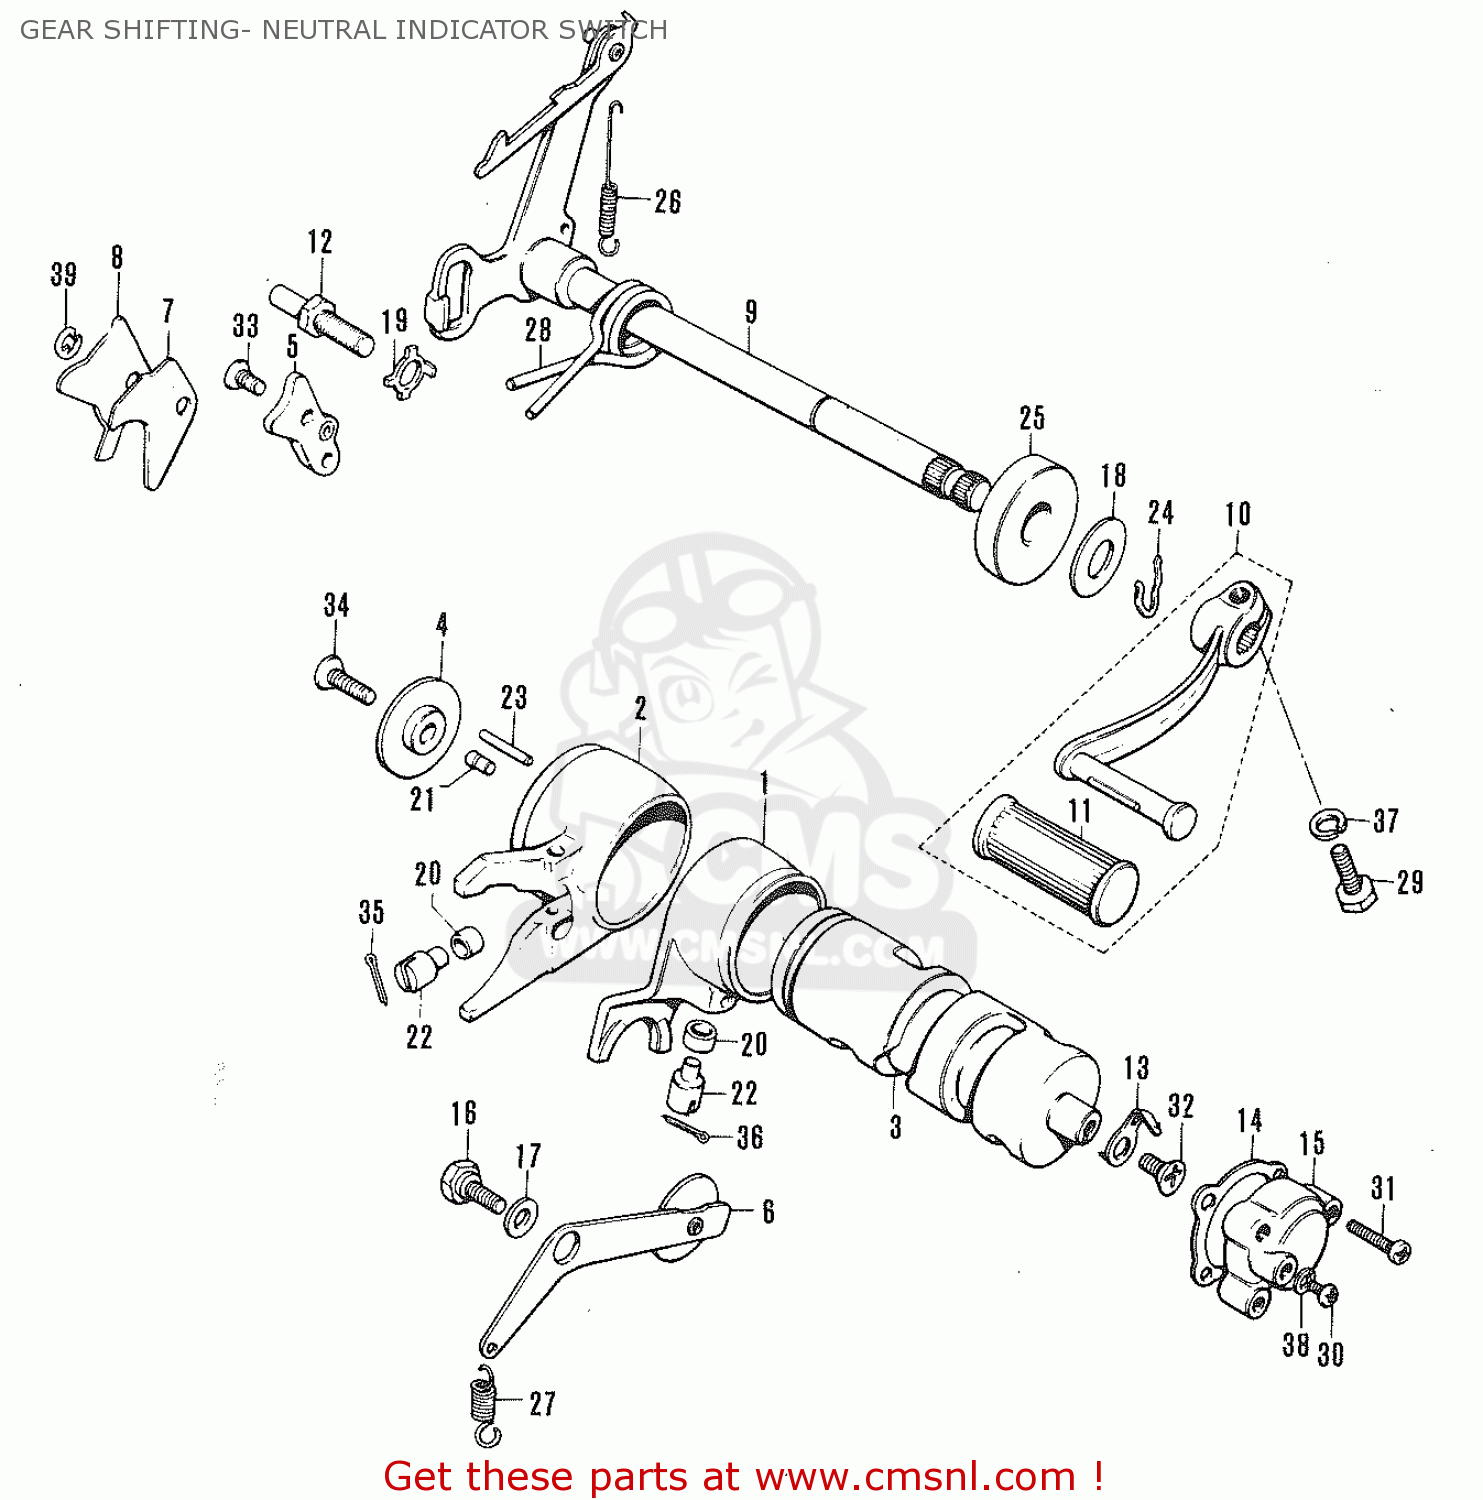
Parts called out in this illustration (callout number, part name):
1	FORK,GEAR SHIFT NO.1
2	FORK,GEAR SHIFT NO.2
3	CAM,GEAR SHIFT
4	HOLDER,GEAR SHIFTING C
5	GUIDE,GEAR SHIFTING CABLE
6	STOPPER,GEAR SHIFT CAM
7	GEAR SHIFTING CAM STOPPER POWL (A)
8	GEAR SHIFTING CAM STOPPER PAWL
9	SHAFT,GEAR SHIFT
10	LEVER ASSEMBLY,GEAR SHIFTING
11	RUBBER,GEAR SHIFT PEDAL
12	STOPPER,GEAR SHIFT ARM
13	NEUTRAL INDICATOR SWITCH CONTACT
14	GASKET,GEAR SHIFT SWITCH (NAS)
15	SWITCH,NEUTRAL INDICATOR
16	BOLT(6X16.1)
17	WASHER (6.5X13X1)
18	WASHER (12.5X27X1.6)
19	WASHER
20	SPACER
21	PIN
22	PIN
23	PIN(4X20)
24	SPRING,RETAINER
25	OIL SEAL
26	SPRING
27	SPRING
28	SPRING
29	BOLT
30	SCREW
31	SCREW
32	SCREW
33	SCREW
34	CROSS HEAD SCREW
35	COTTER PIN
36	PIN 25X20
37	LOCK WASHER
38	WASHER
39	E RING
